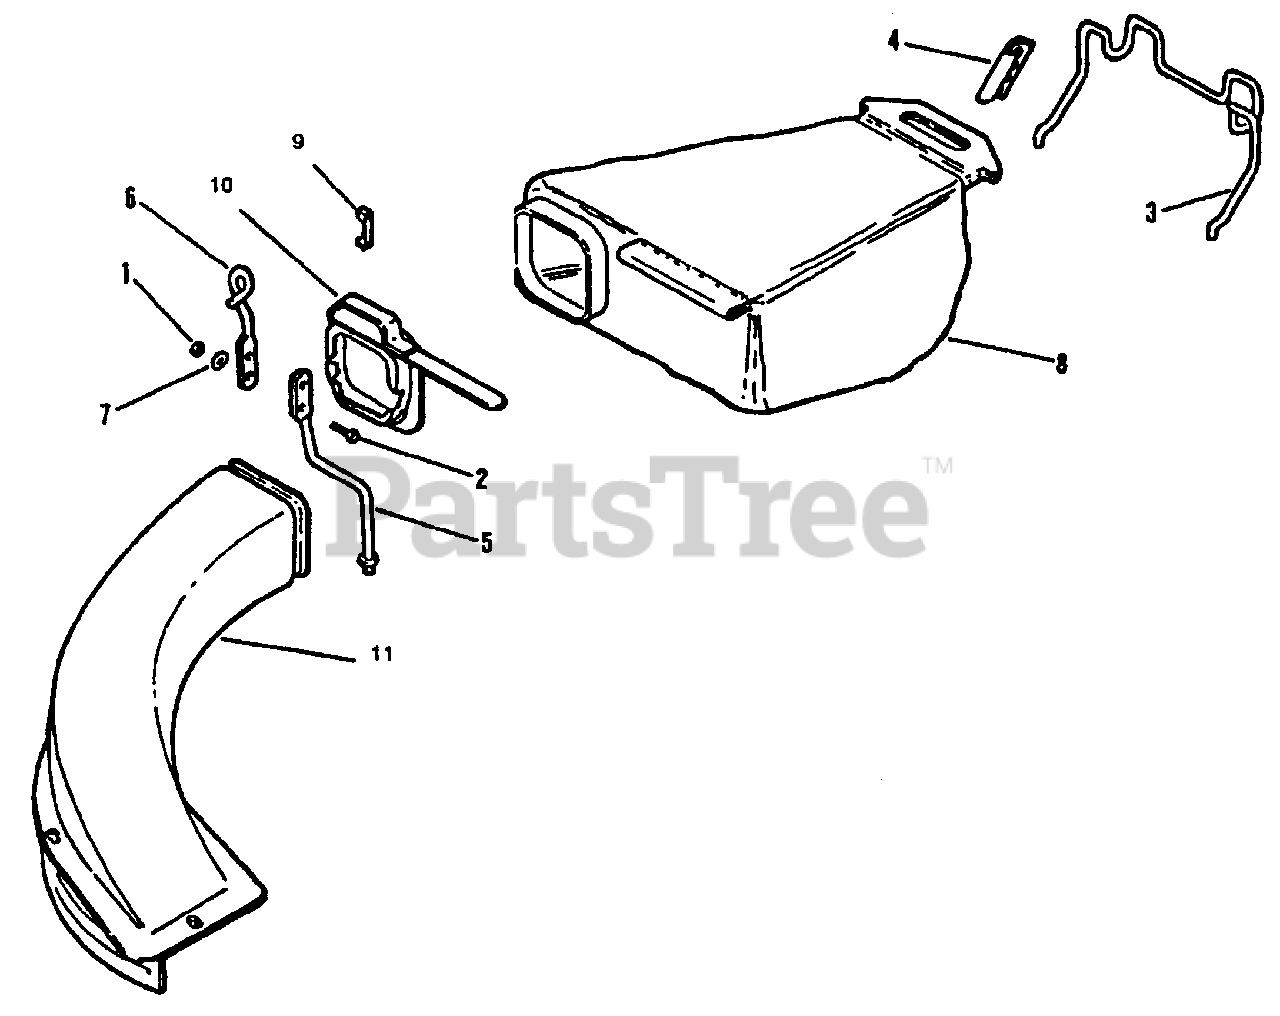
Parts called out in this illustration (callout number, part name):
1	Locknut
3	Wide Hanger
4	Hanger Clamp
5	Chute Support
6	Rope Guide
8	Bag Assembly
9	Strap-Lock
10	Adaptor Assembly
